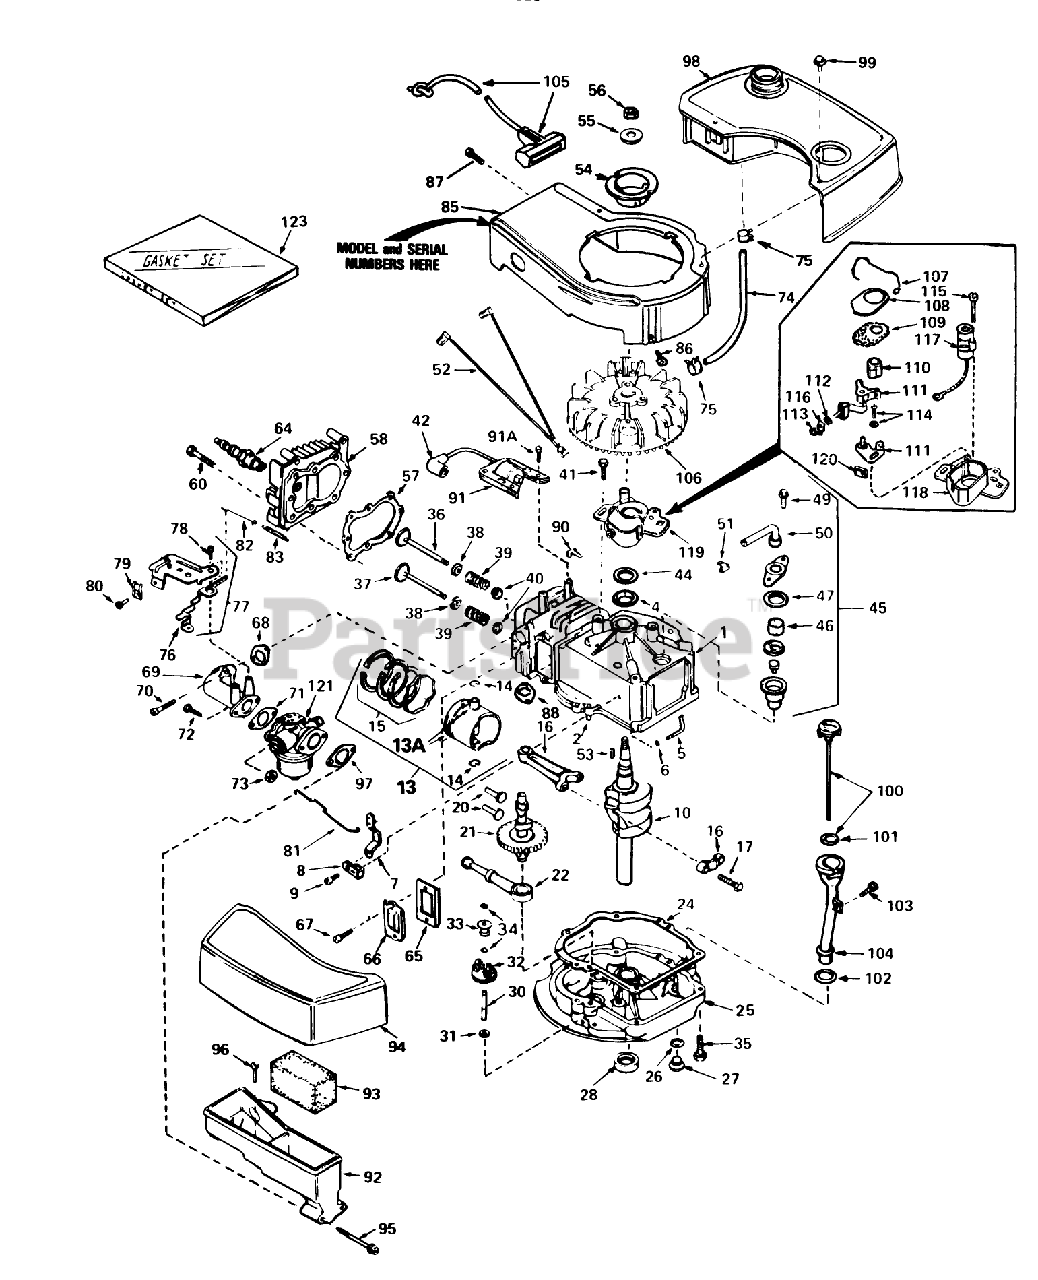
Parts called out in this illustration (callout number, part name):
1	Cyiinder Assy. (Incl. Ref. #2, 4 105)
2	Pin-Dowel
4	Seal-Oil
5	Rod, Governor (Incl. No. 36)
6	Washer-Flat
7	Governor Lever
8	Clamp-Lever, Governor
9	Screw
10	Crankshaft
13	Piston, Pin Ring Assy. (Std.)(Incl. Ref. #13A, 14 15)
13	Piston,Pin Ring Assy. (.010 over-size)(Incl. Ref. #13A, 14 15)
13	Piston, Pin Ring Assy. (Incl. Nos. 13A, 14 15)(.020 oversize)
13A	Piston Pin Assy. (Incl . Ref. . #14) (Std.)
13A	Piston Pin Assy. (Incl. Ref. #14) (.010 Oversize)
13A	Piston Pin Assy. (.020 oversize) (Incl. Ref. #14)
14	Ring-Retaining, Piston Pin
15	Ring Set Piston (Std.)
15	Ring Set Piston (.010 Oversize)
15	Ring Set Piston (.020 Oversize)
16	Rod Assy., Connecting (Incl. Ref. #17)
17	Bolt-Rod, Connecting
20	Lifter-Valve
21	Camshaft(Mech.Comp. Release)
22	Oil Pump ASM
24	Gasket, Mounting
25	Flange Assy., Mounting (Incl. Ref. #26thru 30)
26	Gasket-Oil Drain
27	Plug Oil Drain
28	Seal Oil
30	Shaft-Governor
31	Washer-Flat
32	Governor Gear ASM
33	Spool-Governor
34	Ring-Retaining
35	Screw (1/4-20 x 1-1/4)
36	Valve, Intake (Incl. Ref. #38, 39 40) (Std.)
36	Valve, Exhaust (1/32" Oversize) (Incl. Nos. 8, 9 10)
37	Valve, Exhaust (Standard) (Incl. Nos. 8, 9 10)
37	Valve, Exhaust (1/32" Oversize) (Incl. Nos. 8, 9 10)
38	Cap-Upper Valve Spring
39	Spring-Valve
40	Cap-Valve, Spring
41	Screw
42	Cover-Spark Plug
44	Gasket Stator
45	Breather Assy. (Incl. Ref. #46 thru 51)
46	Element-Breather
47	Gasket-Breather
49	Screw (10-24 x 9/16)
50	Tube, Breaker
51	Clip, Breather
52	Wire Ground
53	682488 LB GRASS HI-
54	Hub-Starter
55	Washer-Belleville
56	Nut-Flywheel
57	63573 GIL 42 SNWTHW
58	Dipper-Oil
60	Screw (5/16-18x1-1/2)
64	Plug, Spark (J17LM or equiv.)
64	Plug, Spark (Champion RCJ-8)
65	Gasket-Breather
66	Cover-Valve
67	Screw
68	Gasket-Intake
69	Pipe, Intake (Incl. No. 68)
70	Screw (1/4-20 x 1)
71	Gasket-Carburetor
73	Nut and Lock Washer (1/4-28)
74	Line-Fuel
75	Clamp-Line, Fuel
76	Lever Control
77	Control Assy., Speed (Incl. Nos, 76, 78 89)
78	Screw, Hex Washer Hd Shoulder Self-Tap
79	Conduit
80	Screw (10-32 x 3/8)
81	Link-Throttle
82	Link Governor Spring
83	Spring Governor
85	Housing Blower
86	Screw
87	Screw (10-24 x 9/16)
88	Gasket Exhaust
90	Clip-Wire
91	Lamination Coil Assy. (Incl. No. 42)
91A	Screw
92	Body Air Cleaner
93	Filer, Air
94	Cove, Air Cleaner
95	Screw Fil Hd.
96	Screw, Hex Hd.
97	Gasket-Air Cleaner
98	Tank, Fuel
99	Screw (10-32 x 35/64)
100	Dipstick, Oil (Incl. Ref. #101)(Twist Lock)
101	O-Ring
102	Gasket
103	Screw (10-32 x 1/2)
104	Tube-Oil Fill
105	Rope Assy., Starter
106	FIywheel
107	Spring Breaker Box
108	Cover-Dust
109	Gasket-Dust Cover
110	Cam-Breaker
111	Breaker Assy.
112	Washer
113	DECAL
114	Breaker Screw
115	Condenser Screw
116	Terminal, Ground
117	Condenser
118	Stator Plate
119	Stator Plate Assy. (incl. Nos. 107, 111 thru 118 120)
120	Felt,Cam Wiper
121	Carburetor (Incl. Ref. #71)
123	Gasket Set
